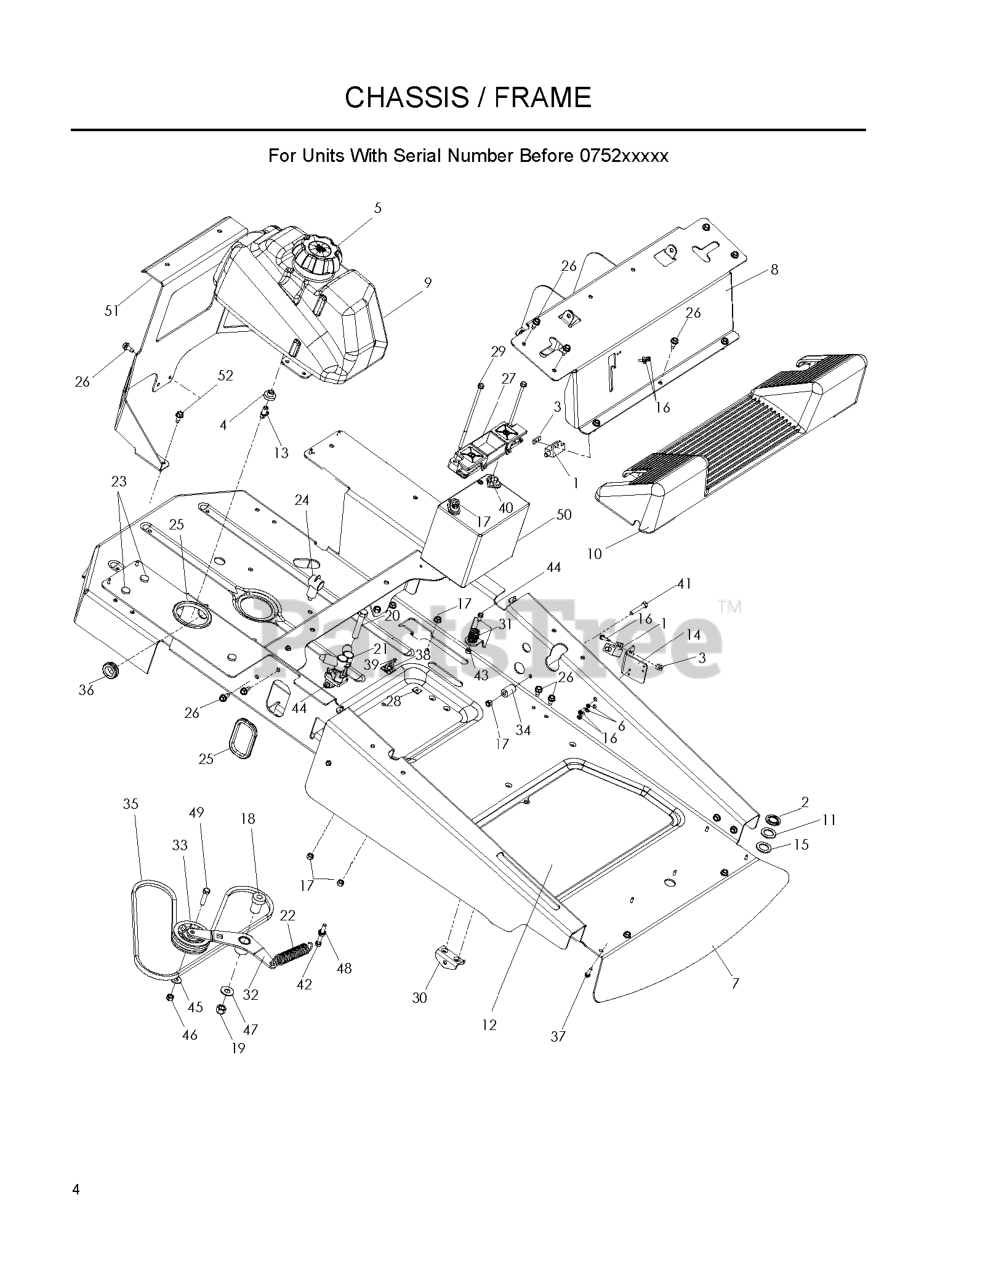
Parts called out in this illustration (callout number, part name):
1	SWITCH, INTERLOCK
2	RETAINING RING, 7/8"
3	TAPPED PLATE
4	RUBBER GROMMET
5	FUEL CAP ANTI-SPLASH
6	WASHER - 3/16 LOCK ZD
7	FRAME W/DECALS
8	SEAT SUPPORT W/DECALS
10	FOOT REST GRAY
12	SLIP, MATTING
13	STEM, FUEL TANK
15	BSHG .875 X 1.375 X .074 ZD
16	SCREW #10-24 X 5/8
17	NUT 5/16 NYLOC
18	IDLER SPINDLE
19	NUT 1/2-13 HEX NYLOC ZD
20	HCS 1/2C X 2 3/4
23	GROMMET, BUMPER
26	BOLT 5/16-18 X 3/4
27	BATTERY HOLD DOWN
28	PUSH NUT-NYLON
29	BOLT - 1/4-20 X 7.5
30	BRACKET, DECK HANGER
31	SPRING, RETURN TO NEUTRAL
32	PUMP IDLER WELDMENT
33	PULLEY, IDLER RAKE & ZTR
34	MOTION LIMITER
35	BELT, HYDRO PUMP
36	GROMMET, FUEL LINE
37	SCR #10-12X1-1/2HEX WASH HD ZD
38	MOUNTING BLOCK CABLE TIE
39	TIE, PLASTIC
40	HCS 5/16C X 3/4
41	HCS 5/16-18X2
43	NUT.1/4-20.HEX.NYLOC.ZD
44	SCREW 1/4 X 5/8
45	WASHER 3/8 FLAT
46	NUT 3/8C CENTERBLOCK
47	WASHER 1/2 FLAT
48	NUT 5/16C WHIZ
49	HCS 3/8C X 1 1/2
50	BATTERY, 12 V 330 AMP
